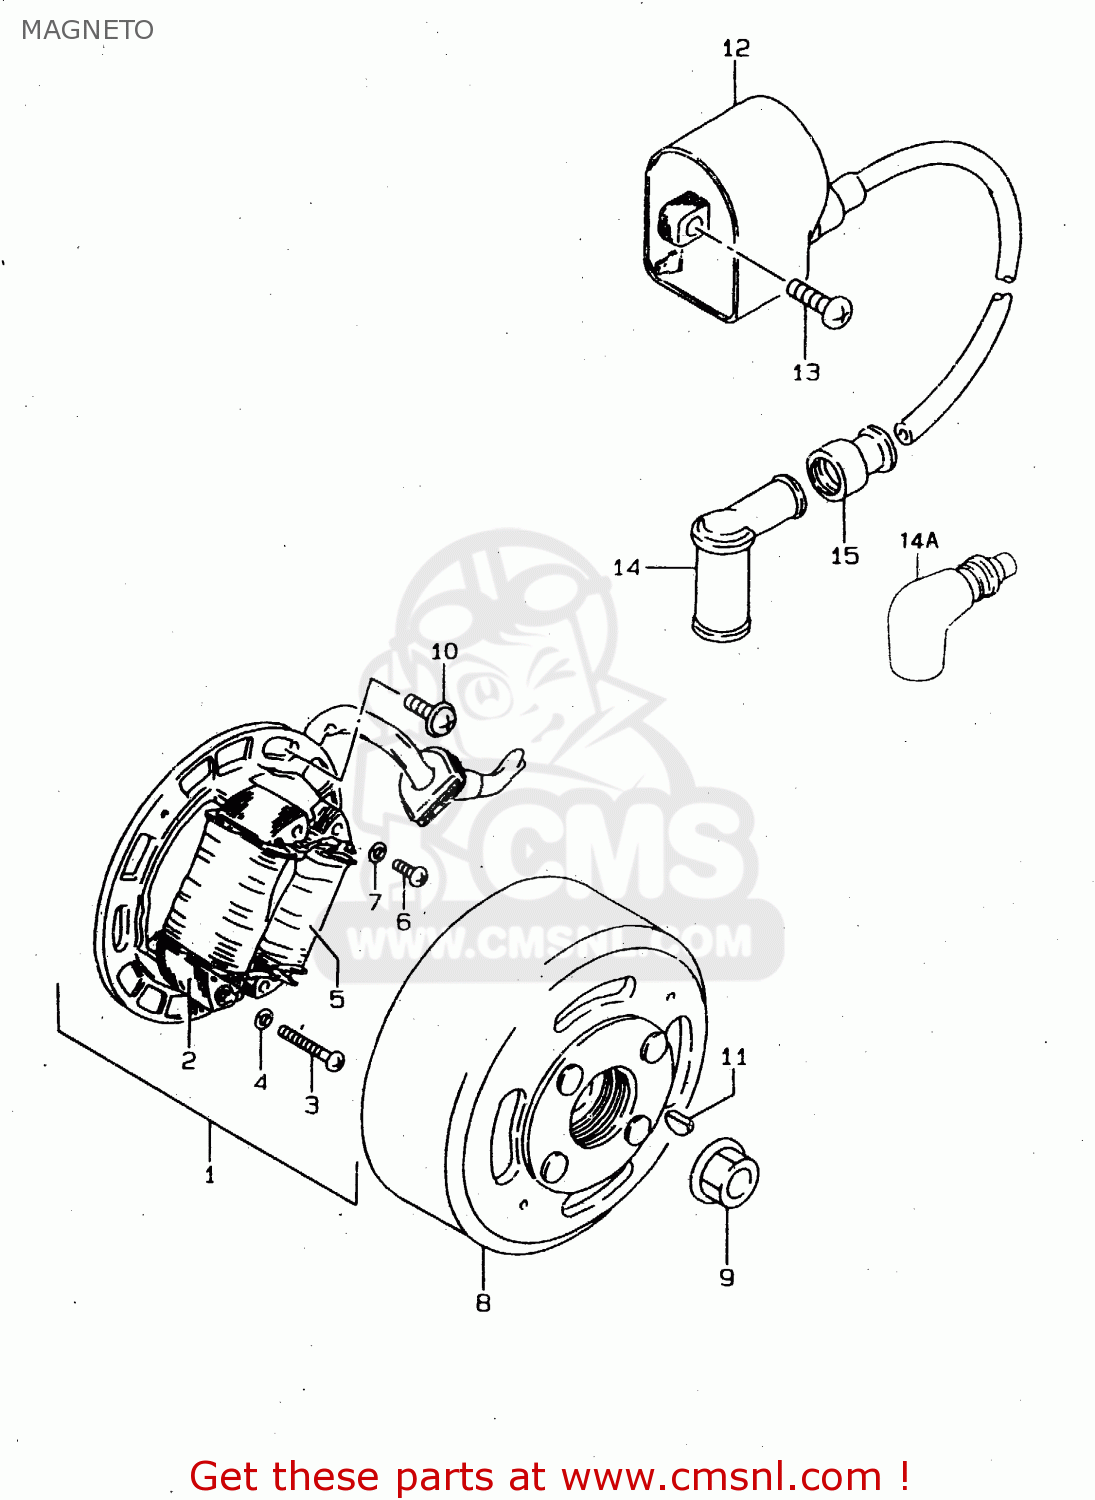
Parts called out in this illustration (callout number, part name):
1	STARTER ASSY
2	COIL,LIGHTING
3	SCREW
4	WASHER,LOCK
5	COIL,PRIMARY
6	SCREW 4X16
7	WASHER,LOCK
8	ROTOR ASSY
9	NUT
10	SCREW 5X12
11	KEY
12	UNIT & COIL ASSY,IGNITION
13	SCREW, 6X20
14	CAP,SPARK PLUG
14A	CAP,SPARK PLUG
15	SEAL,HIGH TENSION CORD
